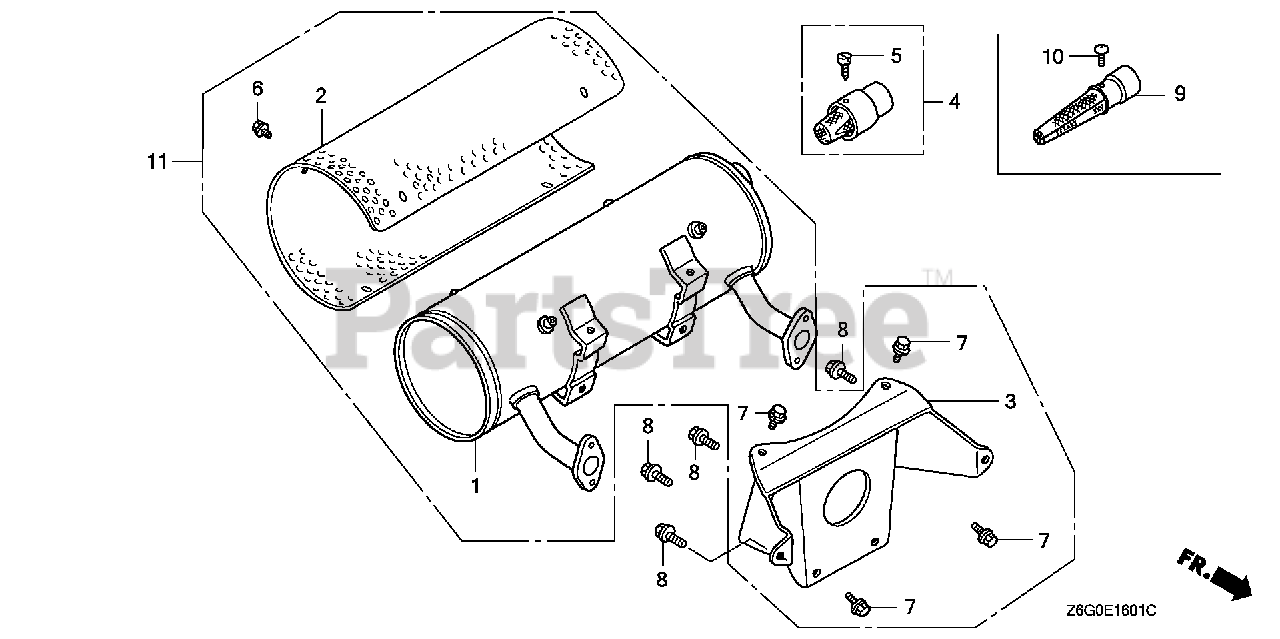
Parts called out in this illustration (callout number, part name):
1	MUFFLER COMP. (HIGH-L) (FUTABA) (SILVER MUFFLER) (FOR SILVER MUFFLER)
2	PROTECTOR, MUFFLER (HIGH) (FUTABA) (FOR SILVER MUFFLER)
3	STAY, MUFFLER (HIGH-FUTABA) (FOR SILVER MUFFLER)
6	BOLT, FLANGE (6X8)
7	BOLT, FLANGE (8X14)
8	BOLT, FLANGE (8X20)
9	ARRESTER, SPARK (FOR SILVER MUFFLER)
10	SCREW, TAPPING (5X8) (FOR SILVER MUFFLER)
11	MUFFLER ASSY. (HIGH-L) (FUTABA) (SILVER MUFFLER)
